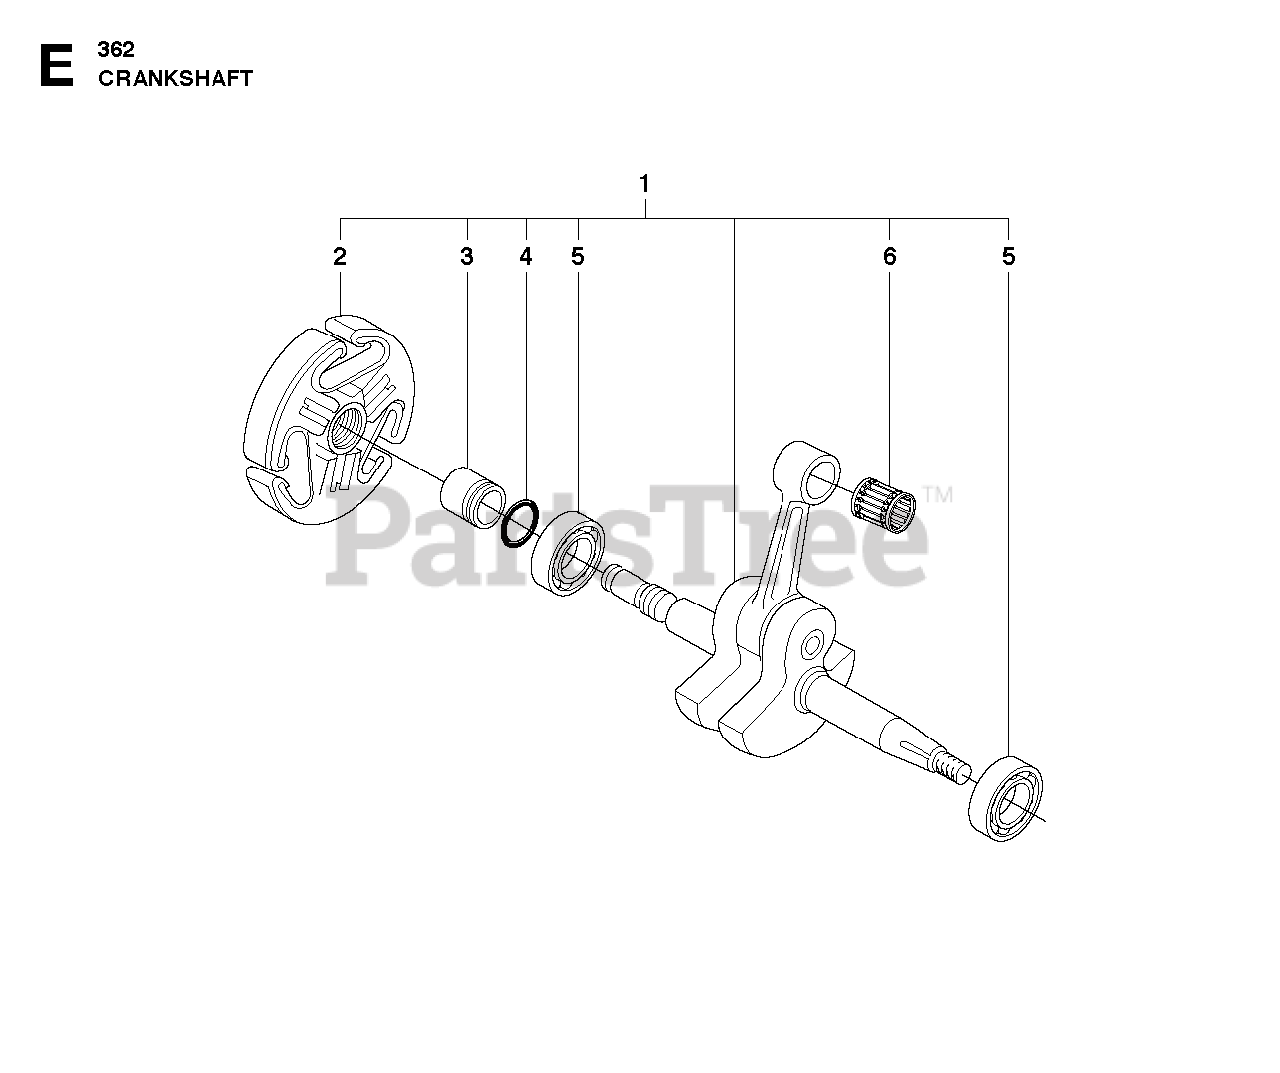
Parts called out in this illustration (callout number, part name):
1	CRANKSHAFT COMPLETE
2	CLUTCH
3	SLEEVE
4	O-RING
5	BALL BEARING-6202-C3 SKF
6	SUPPORT BUSHING
